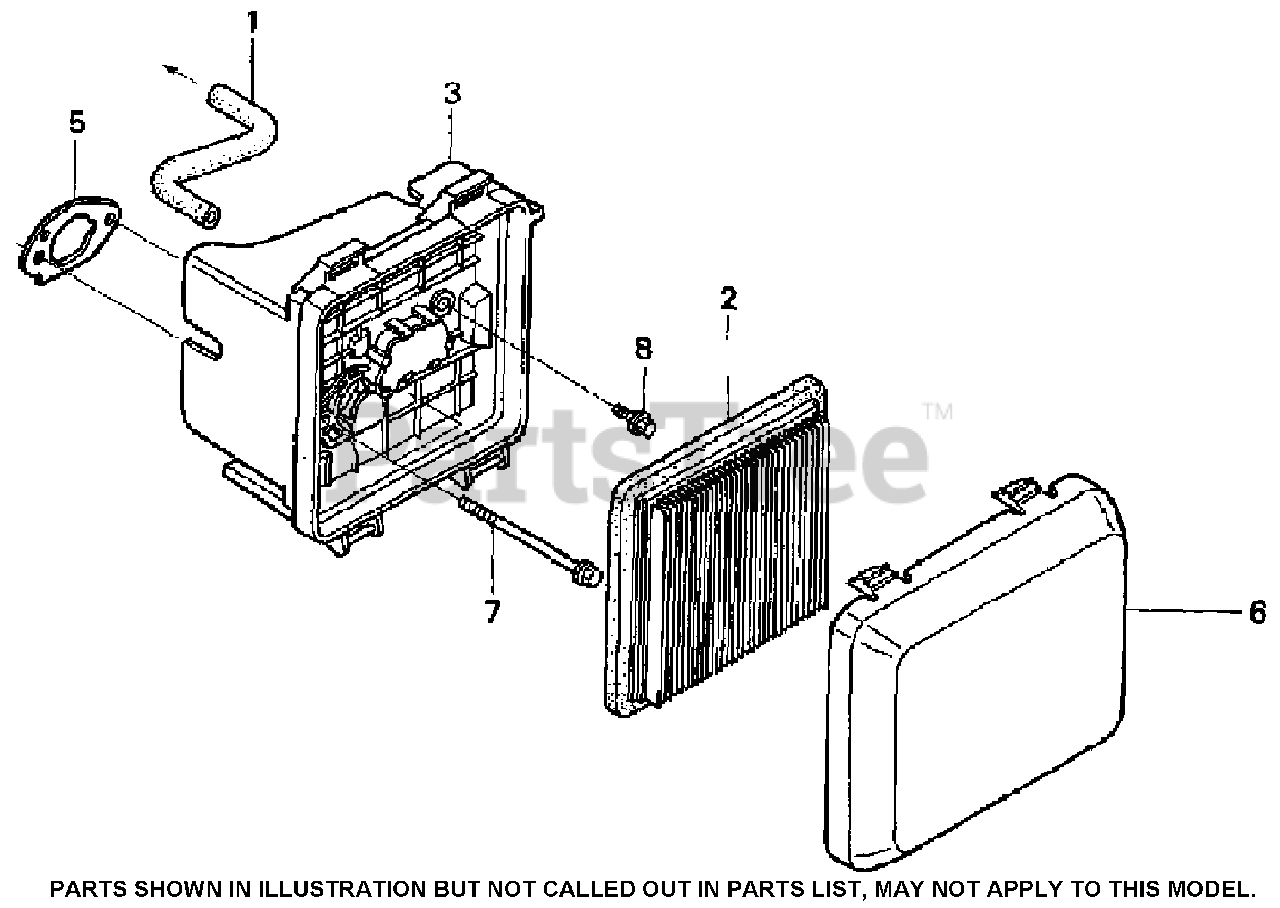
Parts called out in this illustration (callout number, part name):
1	TUBE, BREATHER
2	ELEMENT-AIR CLEANER
3	CASE ASM., AIR CLEANER
5	GASKET, AIR CLEANER
6	COVER, AIR CLEANER
8	BOLT-FLANGE
9	BOLT, FLANGE (6X86) (CT200)
